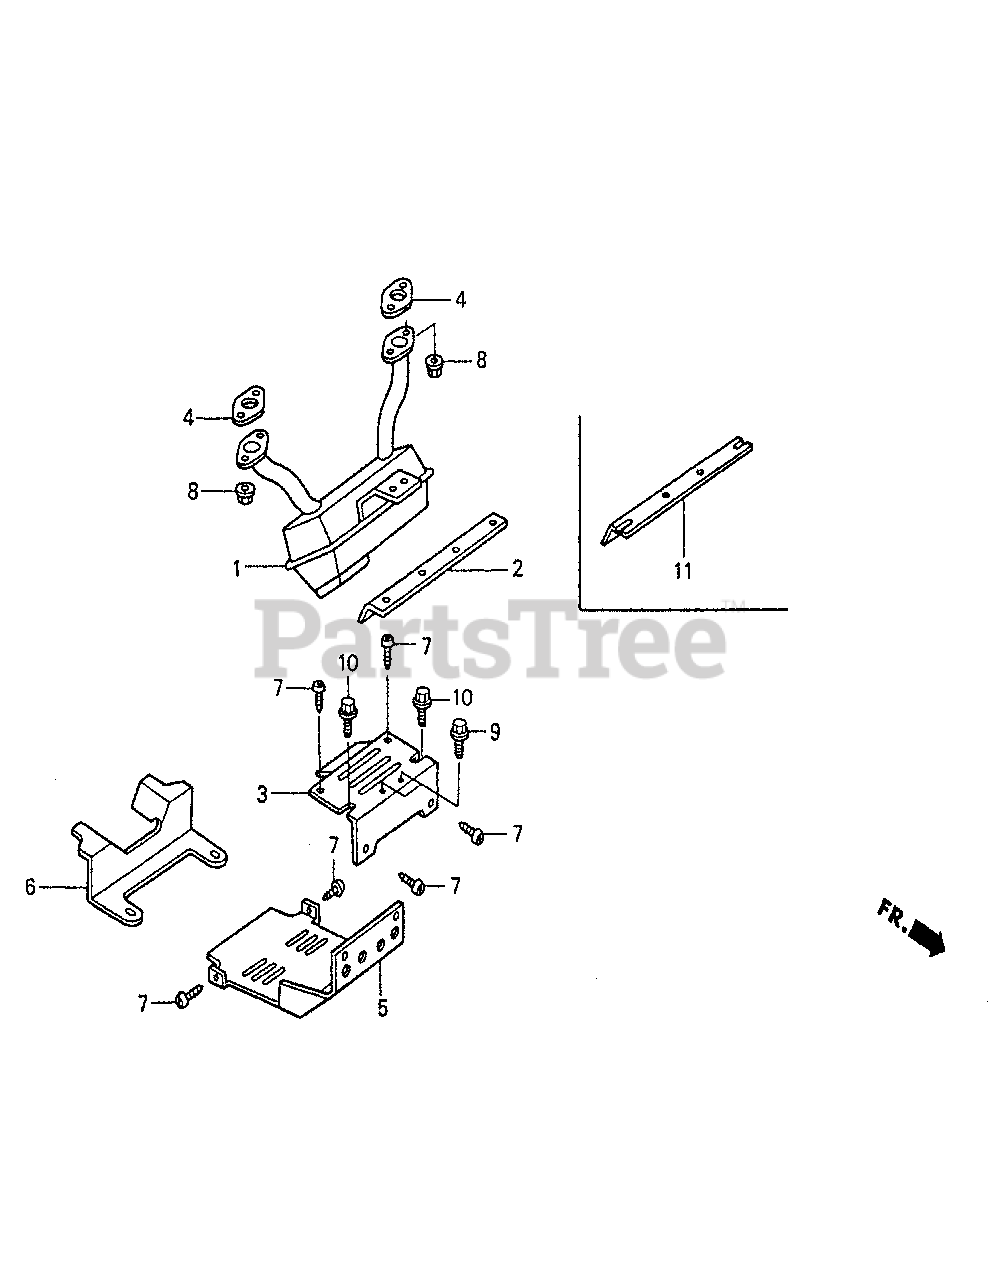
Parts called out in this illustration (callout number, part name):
2	PLATE, MUFFLER SUPPORT
3	PROTECTOR, MUFFLER (UPPER)
4	GASKET, EX. PIPE
5	GUARD, MUFFLER PROTECTOR
6	GUARD, EX. PIPE
7	HEIGHT ADJUST SET
8	NUT, FLANGE (8MM)
9	BOLT, FLANGE (8X25)
9	SCREW, SELF-TAPPING (8MM)
10	BOLT, FLANGE (8X16) (19M7867)
10	BOLT, FLANGE (8X25)
11	PLATE, MUFFLER SUPPORT (NOT AVAILABLE)
